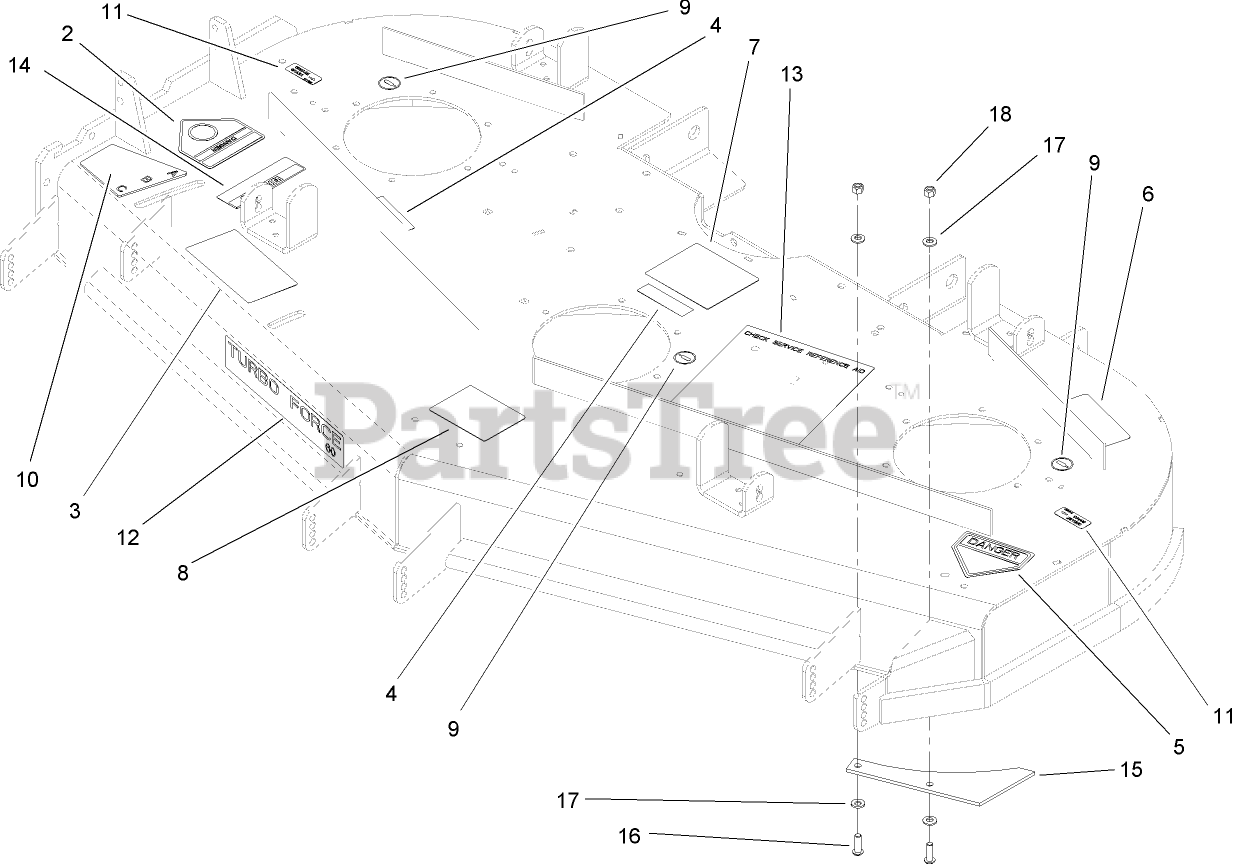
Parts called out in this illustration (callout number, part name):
2	DECAL-DANGER
3	DECAL-DANGER, THROWN OBJECT
4	DECAL-COVER, MISSING
5	DECAL-DANGER
6	DECAL-TORQUE
7	Decal-Routing, Belt
8	DECAL-SCALP, ANTI
9	DECAL-GREASE
10	DECAL-ADJUSTMENT, BAFFLE
11	Decal-Grease
13	Decal-Service, Check
14	DECAL-WARNING
15	PLATE-TURBO
16	SCREW-HSBH
17	WASHER-SPRING
18	NUT-LOCK, NI
